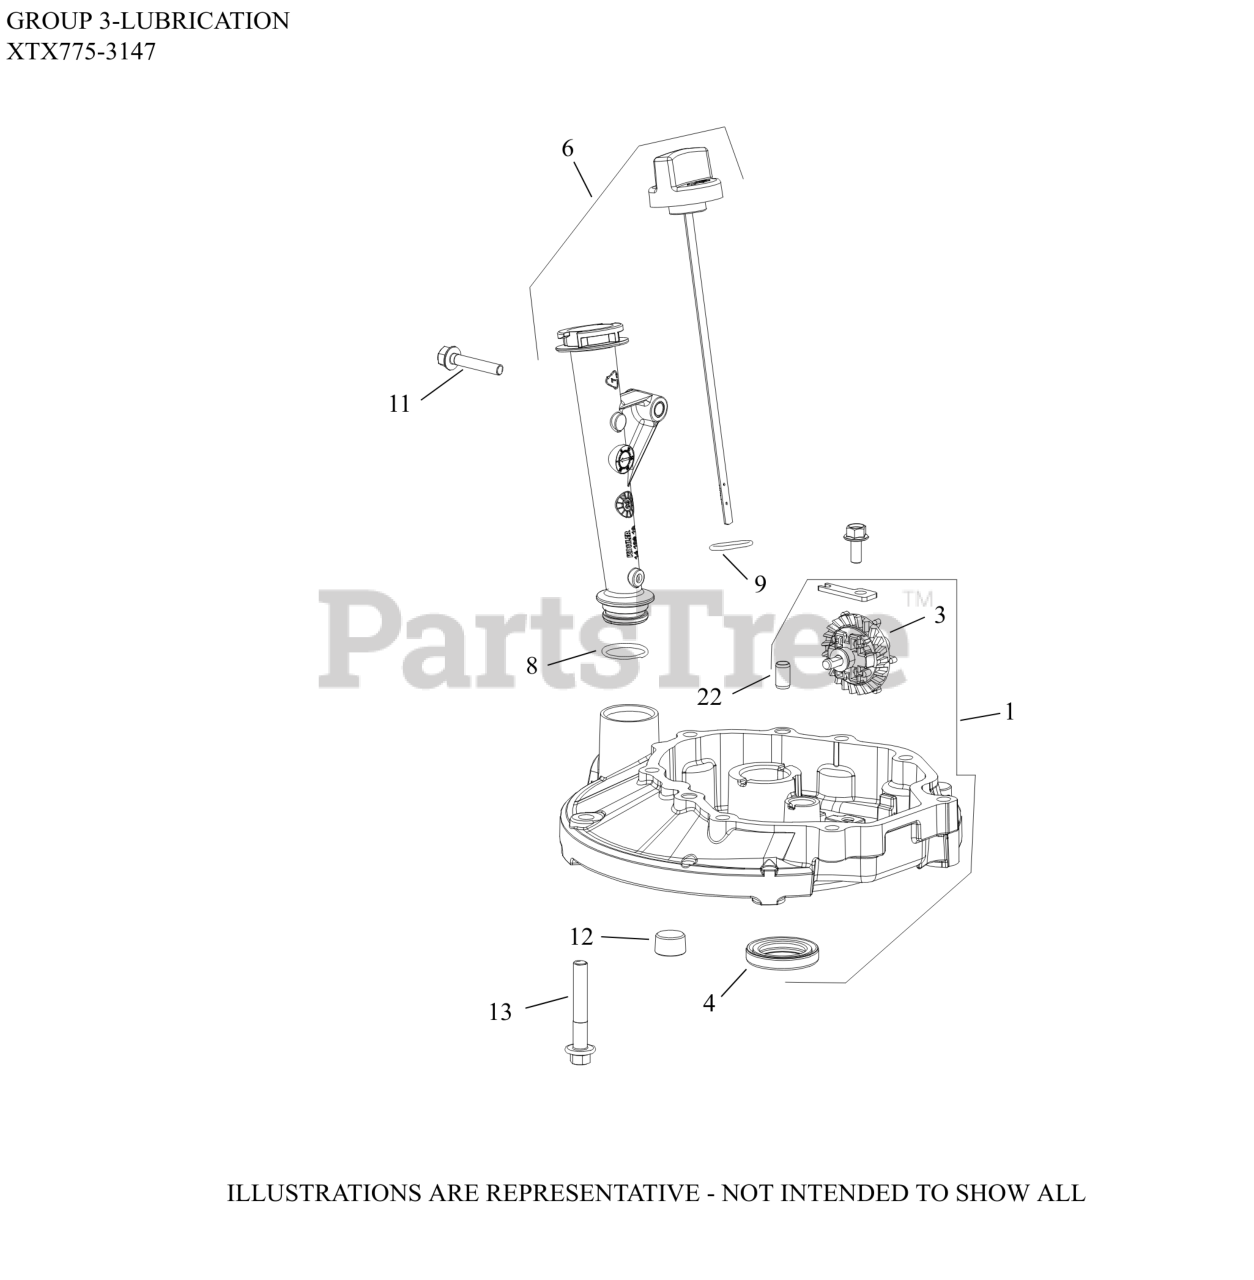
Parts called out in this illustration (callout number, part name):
1	KIT, OIL PAN
3	GEAR ASSEMBLY, GOVERNOR
6	TUBE ASSEMBLY OIL FILL
8	O-RING, OIL FILL TUBE
9	O-RING (CAP)
11	SCREW, HEX FLANGE (M6)-(#25086435S)
12	PLUG, PIPE (W/SEALANT)
13	SCREW, HEX FLANGE (M8)-USE 25 086 456-S
22	PIN, DOWEL (8mm)
